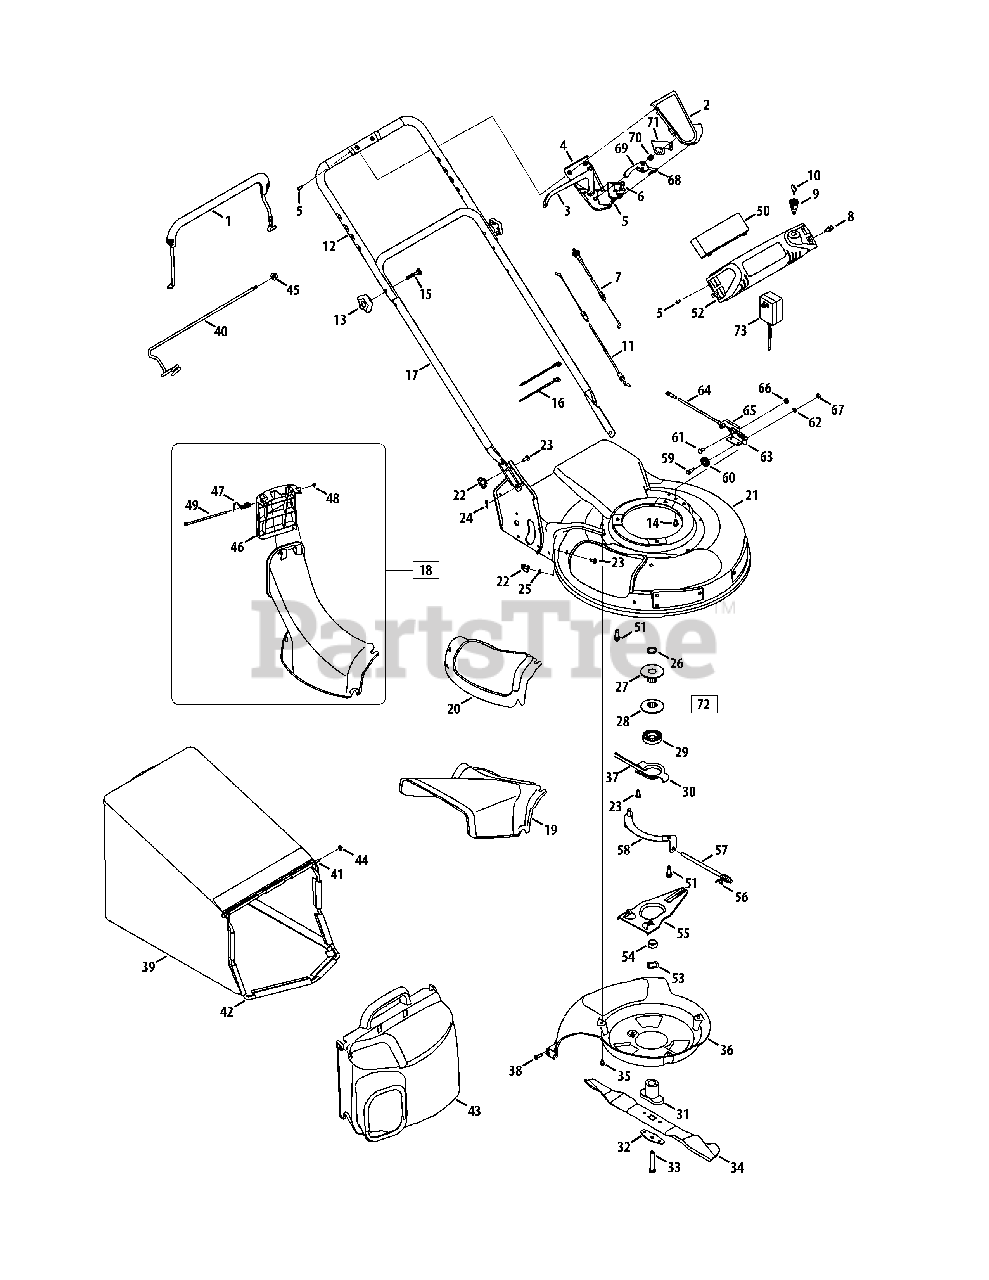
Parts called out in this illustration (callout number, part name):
1	Blade Control
2	Upper Control Housing
3	Drive Control
4	Lower Control Housing
5	C Sunk Tap Screw, #10 x.75 Lg
6	Cable Mounting Cap
7	Drive Cable
9	Key Switch
11	Control Cable
14	Screw, 1/4-20 x .625
15	Carriage Bolt, 5/16-18 x 2.0
16	Cable Tie
18	Adapter Assembly
19	Side Discharge Chute
20	Mulch Cover
22	Wing Nut
23	Carriage Bolt, 1/4-20 x .75"
24	Cotter Pin
25	Push Nut, .25 x ID x .50 OD
26	Sleeve Spacer, .88ID x 1.13OD
27	Half Pulley: 2.62 OD
28	Half Pulley: 2.62 OD x 1.61
29	Ball Bearing
31	Blade Adapter
32	Blade Bell Support
33	Hex Bolt, 3/8-24 x 2.5
34	21" Mulching Blade
35	Screw, 1/4-20 x 3.75
36	Baffle
37	Belt, 3/8 x 39.24
38	Screw, 1/4-15 x .750
39	Grass Catcher
40	Support Rod w/ Rope Guide
41	Pivot Rod
42	Grass Catcher Frame
43	Grass Catcher Cover
44	Cap Nut
45	Flange Lock Nut, 5/16-18
46	Chute Door
47	Torsion Spring
49	Pivot Rod
50	12V Battery
51	Sems Screw, 3/8-16 x 1.00
52	Harness Assembly
53	Wave Washer, 1.38 ID x.88 OD
54	Slve Spacer, .88 ID x 1.00 OD
57	Pivot Shaft
59	Shlder Screw, .375 ID x 1/4-14
60	Cable Roller
61	Carriage Screw, 1/4-20 x .62
62	Lock Washer, 1/4
63	Cable Mounting Bracket
64	6 Speed Cable
65	Cable Adjustment Bracket
66	Hex Nut 1/4-20
67	Hex Nut 1/4-28
68	Shift Lever Spring
69	6 Speed Shift Lever
70	Gear Insert
71	6 Spd. Rack Cable Bracket
72	Pulley Assembly
73	12V Battery Charger
